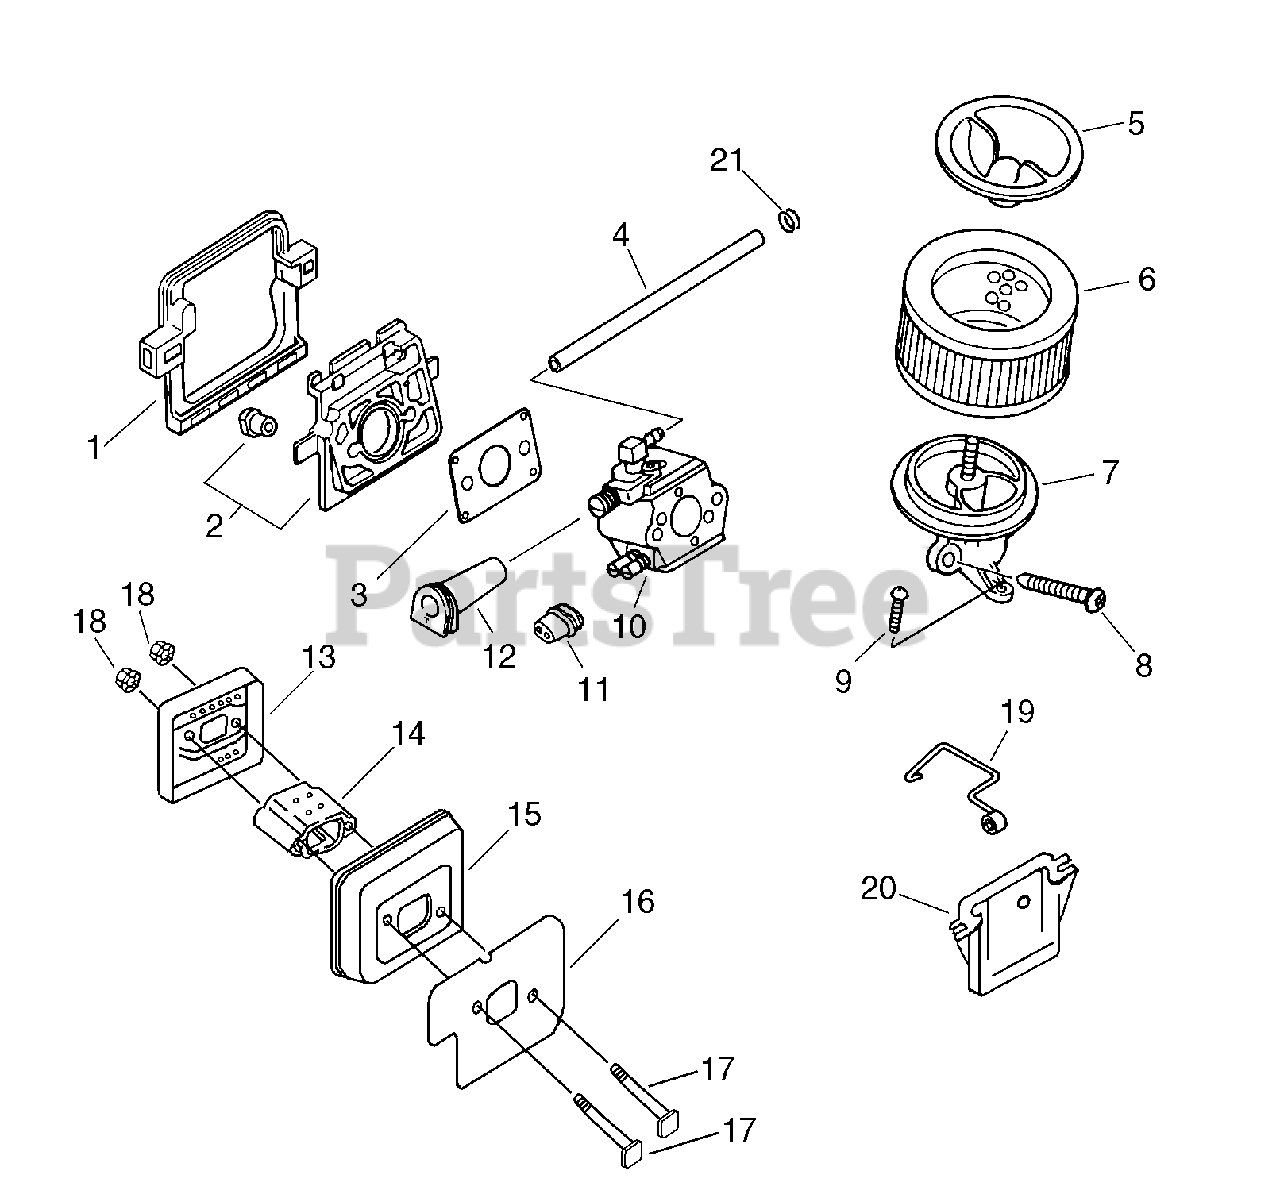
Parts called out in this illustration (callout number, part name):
1	CUSHION
2	INSULATOR
3	GASKET, INTAKE
4	PIPE, FUEL 3×6×105 BLACK
5	COVER, AIR FILTER
6	FILTER, HEAVY-DUTY AIR
7	ADAPTER, INTAKE
8	SCREW 5×50
9	SCREW 5×16
10	CARBURETOR
13	COVER, MUFFLER
14	PLATE, MUFFLER
16	GASKET, MUFFLER
18	NUT, FLANGE M5
19	ROD, THROTTLE
20	GUIDE, THROTTLE ROD
21	CLIP 6 MM
